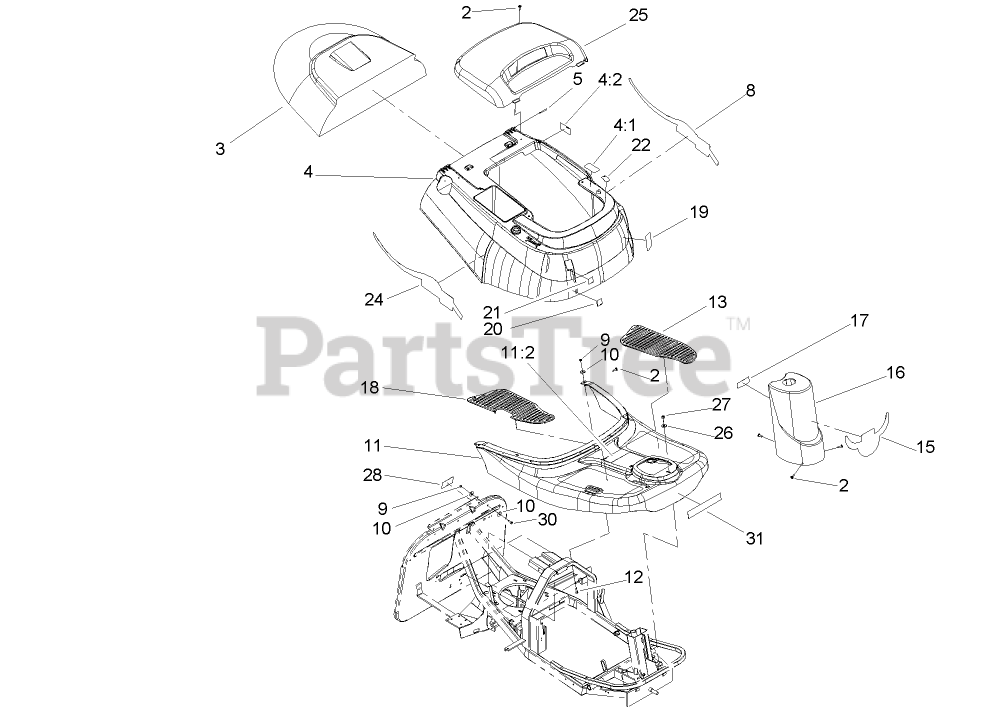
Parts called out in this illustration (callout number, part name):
2	Screw-HH, TAP
3	COVER-GRASS BAG
4	Shroud And Decal ASM
4:1	Decal-Danger
4:2	Loose Parts Package
5	Pin-Dowel
8	DECAL-SIDE, LEFT
10	Washer-Flat
11	FOOT REST AND DECAL ASM
11:2	Loose Parts Package
12	SCREW-HH
13	Floormat-LH
15	DECAL-FRONT
16	Steering-Turret
17	Loose Parts Package
18	Floormat-RH
19	Loose Parts Package
20	Loose Parts Package
21	Loose Parts Package
22	Loose Parts Package
24	DECAL-SIDE, RIGHT
25	Cover-Engine
26	Washer-Flat
27	NUT-LOCK
28	Loose Parts Package
30	SCREW-HH
